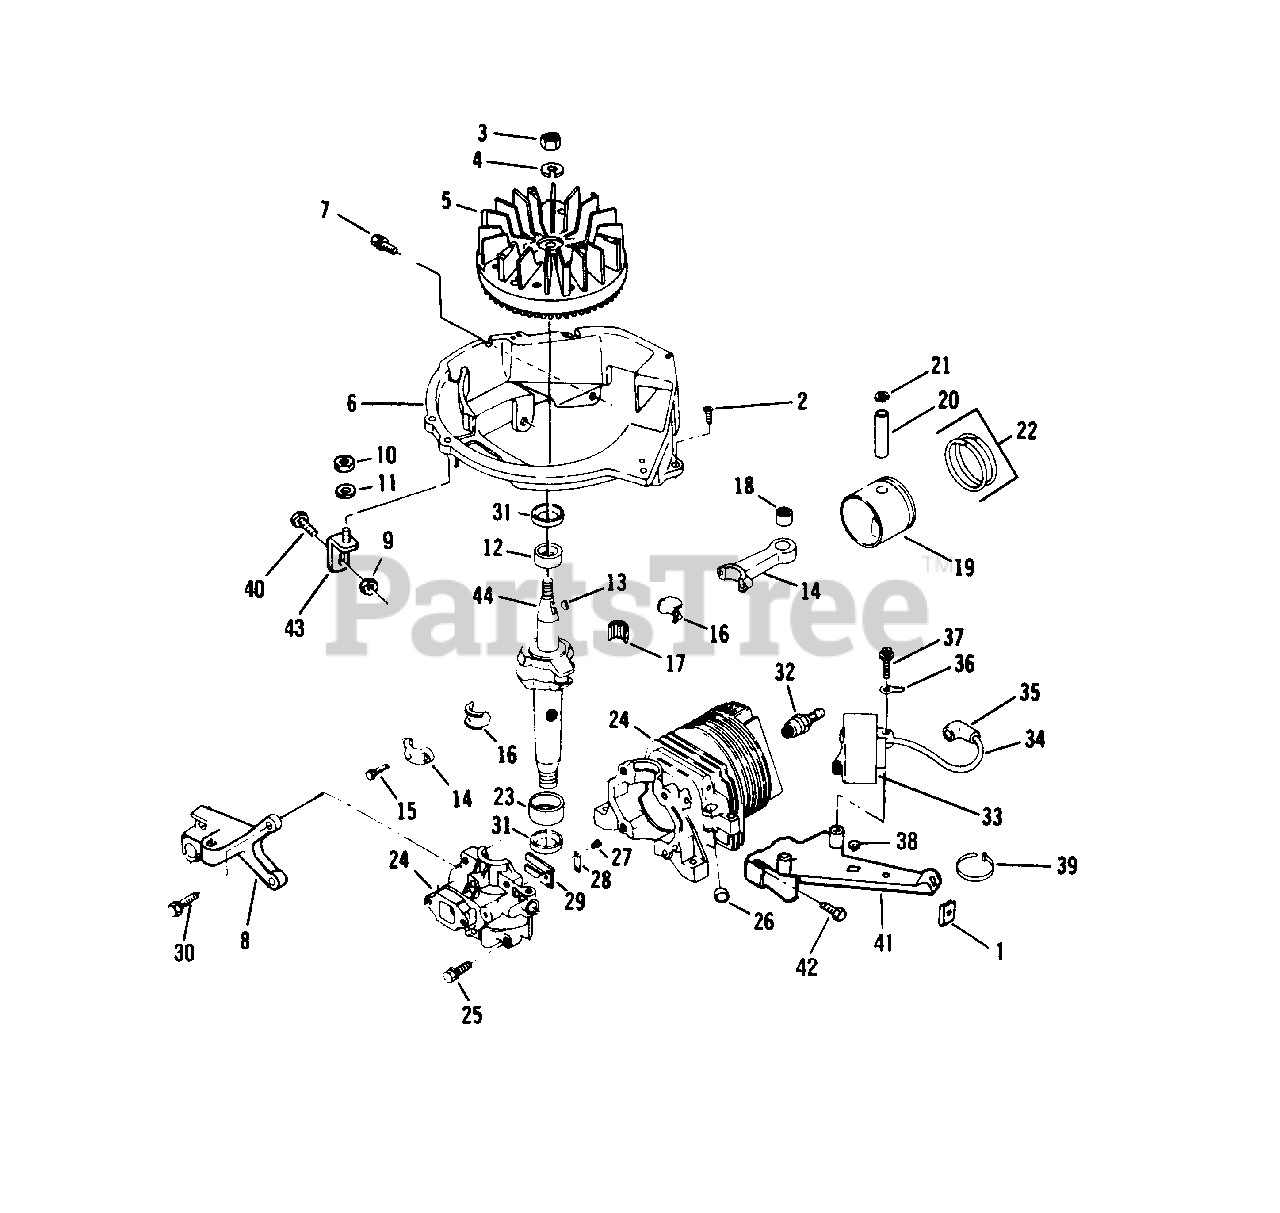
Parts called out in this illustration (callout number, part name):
1	Speednut
2	Screw-Shroud Base to C.D. Brkt.
3	Nut-Flywheel
4	Lockwasher
5	Flywheel Assembly
6	Base-Shroud
7	Screw
8	Bracket-Brake
9	Nut
10	Nut
11	Washer
12	Bearing-Main-Upper
13	Key-Flywheel
14	Connecting Rod Assembly
15	Screw-Cap
16	Liner Split
17	Needle Bearing Set
18	Bearing Assembly
19	Piston and Ring Set
20	Wrist Pin
21	Retaining Ring
22	Ring Set
23	Bearing-Main-Lower
24	Cylinder and Crankcase Cover Assembly
25	Screw-Cover to Crankcase
26	Plug
27	Screw-Reed to Crankcase Cover
28	Plate-Reed Hold Down
29	Reed
30	Screw-Brake Mouting Bracket
31	Oil Seal
32	Spark Plug
33	C.D. Ignition Module and Lead Assembly
34	High Tension Lead and Lower Assembly
35	Spring Terminal
36	Terminal-Ground Lead
37	Screw-C.D. Mounting
38	Grommet-C.D. Bracket
39	Tie Strap
40	Bolt
41	Bracket-C.D. Mouting
42	Screw
43	Brace Assembly
44	Crankshaft
